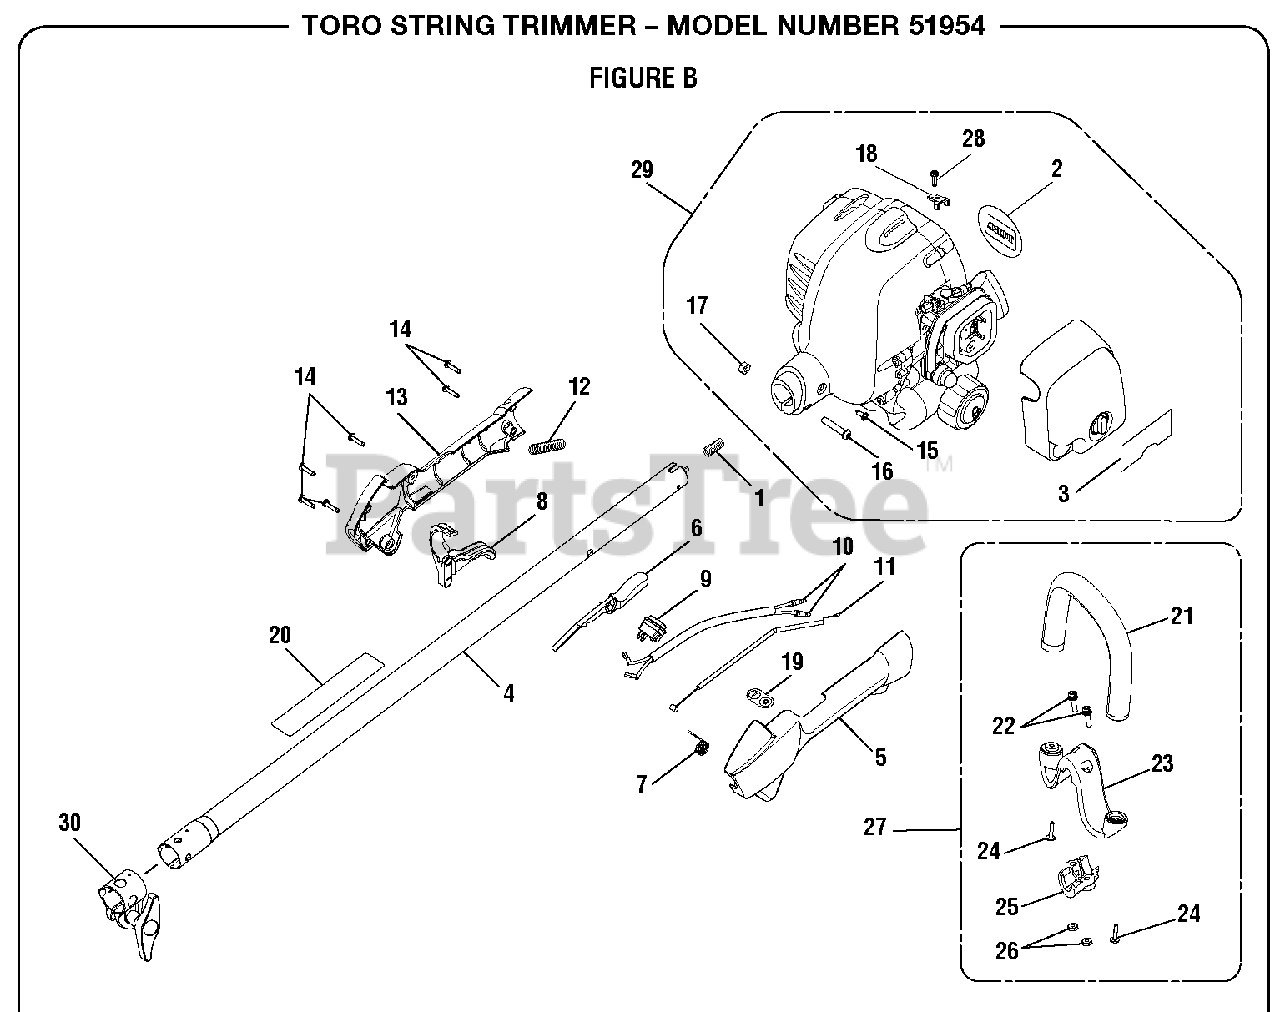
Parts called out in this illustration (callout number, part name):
1	Compression Spring
2	Logo Plate
3	Lower Start Label
4	Upper Shaft Assembly (Inc. Key Nos. 20 and 30)
5	Rear Handle Support
6	Lock-off Button
7	Trigger Spring
8	Trigger
9	Switch w/ Dust Shield
11	Cable, Throttle
12	Corrugated Tube
13	Rear Handle Cover
14	Screw (M4 x 16 mm)
15	Screw (#8-16 x 1/2 in. Tri-Lobular)
16	Screw (M6 x 1-30 mm)
17	Hex Nut (M6.3 x 1)
18	Throttle Cable Clamp
19	On/Off Label
20	Warning Label
21	Front Handle w/Grip
22	Screw (#12-24 x 1 in., Slotted Torx)
24	Screw (10-14 x 1 in.)
25	Clamp
26	Hex Nut (12-24)
27	Front Handle Assembly
28	Screw (M4 x 16 mm)
29	Powerhead Assembly
30	Boom Clamp
